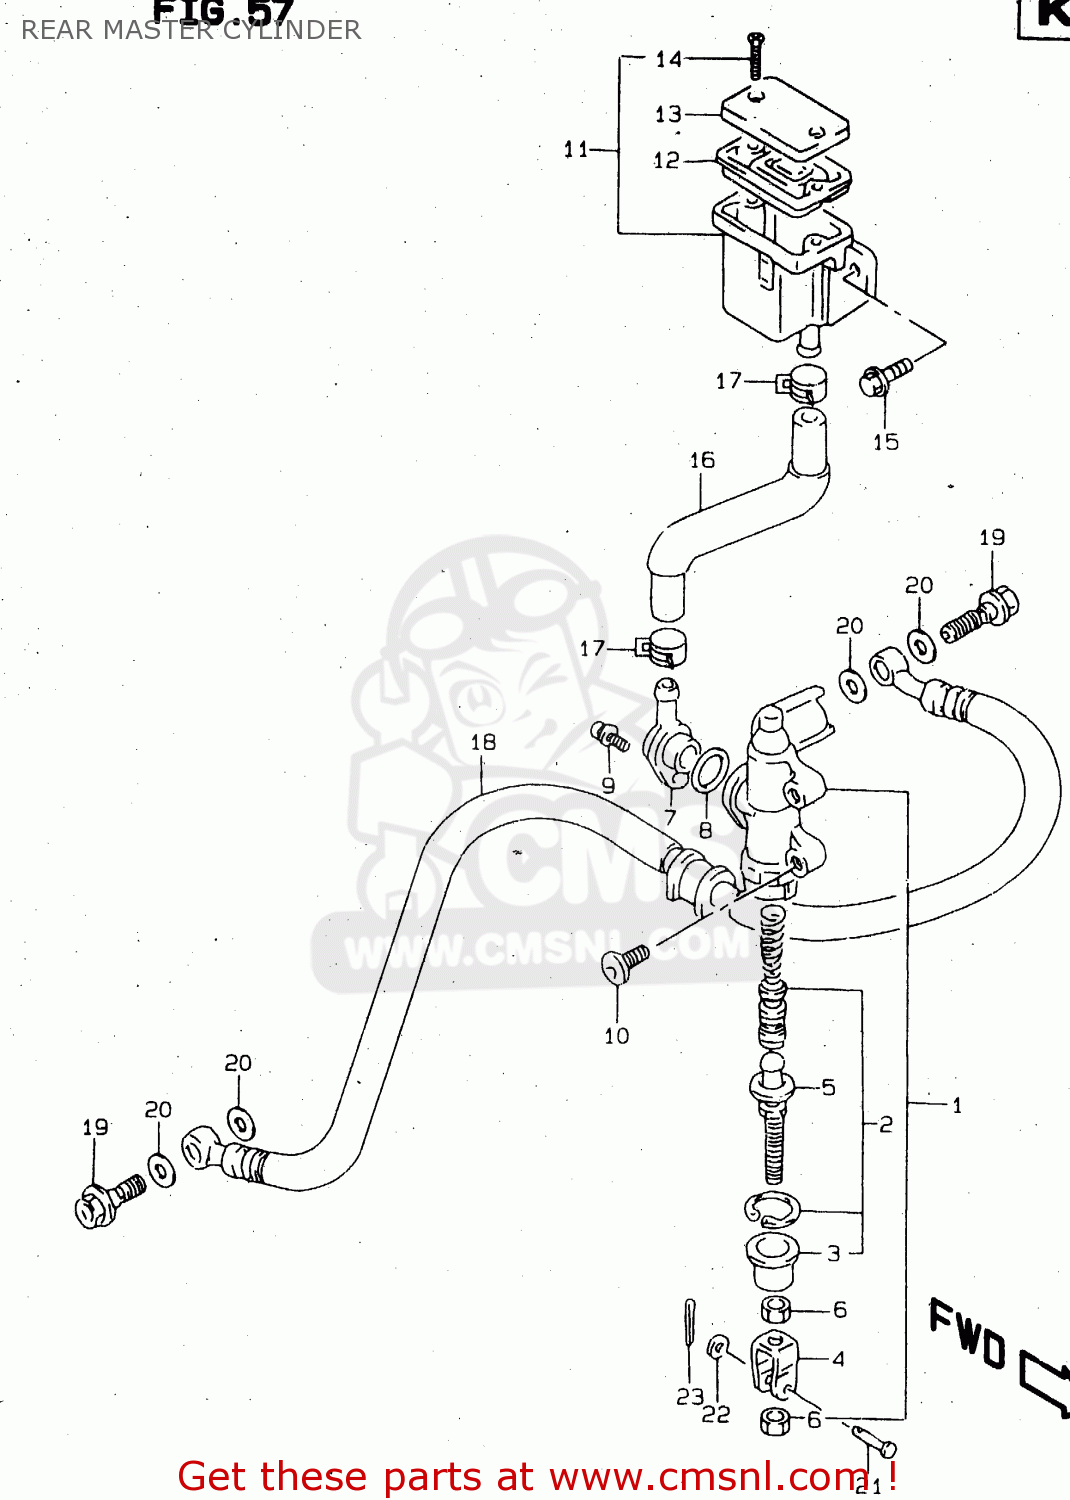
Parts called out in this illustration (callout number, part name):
1	CYLINDER ASSY,RR MASTER
2	PISTON/CUP SET
3	BOOT
4	YOKE
5	ROD,PUSH
6	NUT
7	CONNECTOR
8	O RING
9	SCREW
10	SCREW(6X25)
11	TANK ASSY,RESERVOIR
12	DIAPHRAGM
13	CAP
14	SCREW
15	BOLT
16	HOSE,RESERVOIR TANK
17	CLIP
18	HOSE,RR BRAKE
19	BOLT UNION
20	WASHER(10X15X1.5)
21	PIN
22	WASHER
23	PIN
